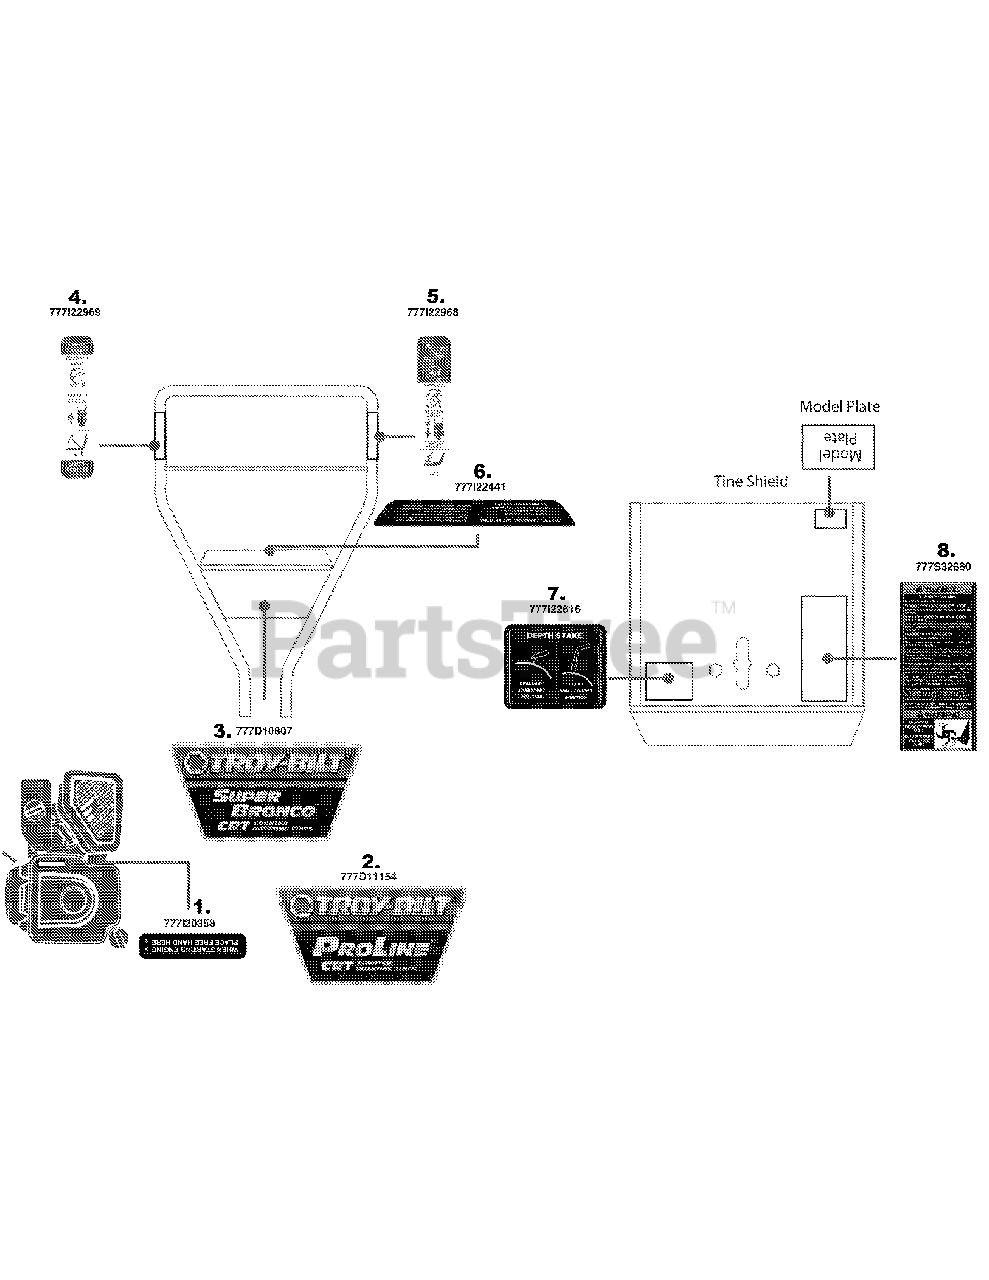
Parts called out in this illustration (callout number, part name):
1	LABEL-PLACE HAND HERE
2	LABEL-TILLER HANDLE TROY PRO LINE
3	LABEL-TILLER HANDLE TROY CRT
6	LABEL-HNDL PNL INST CRT
7	LABEL:TILLER TINE SHIELD DEPTH
8	LABEL:TILLER TINE SHIELD
